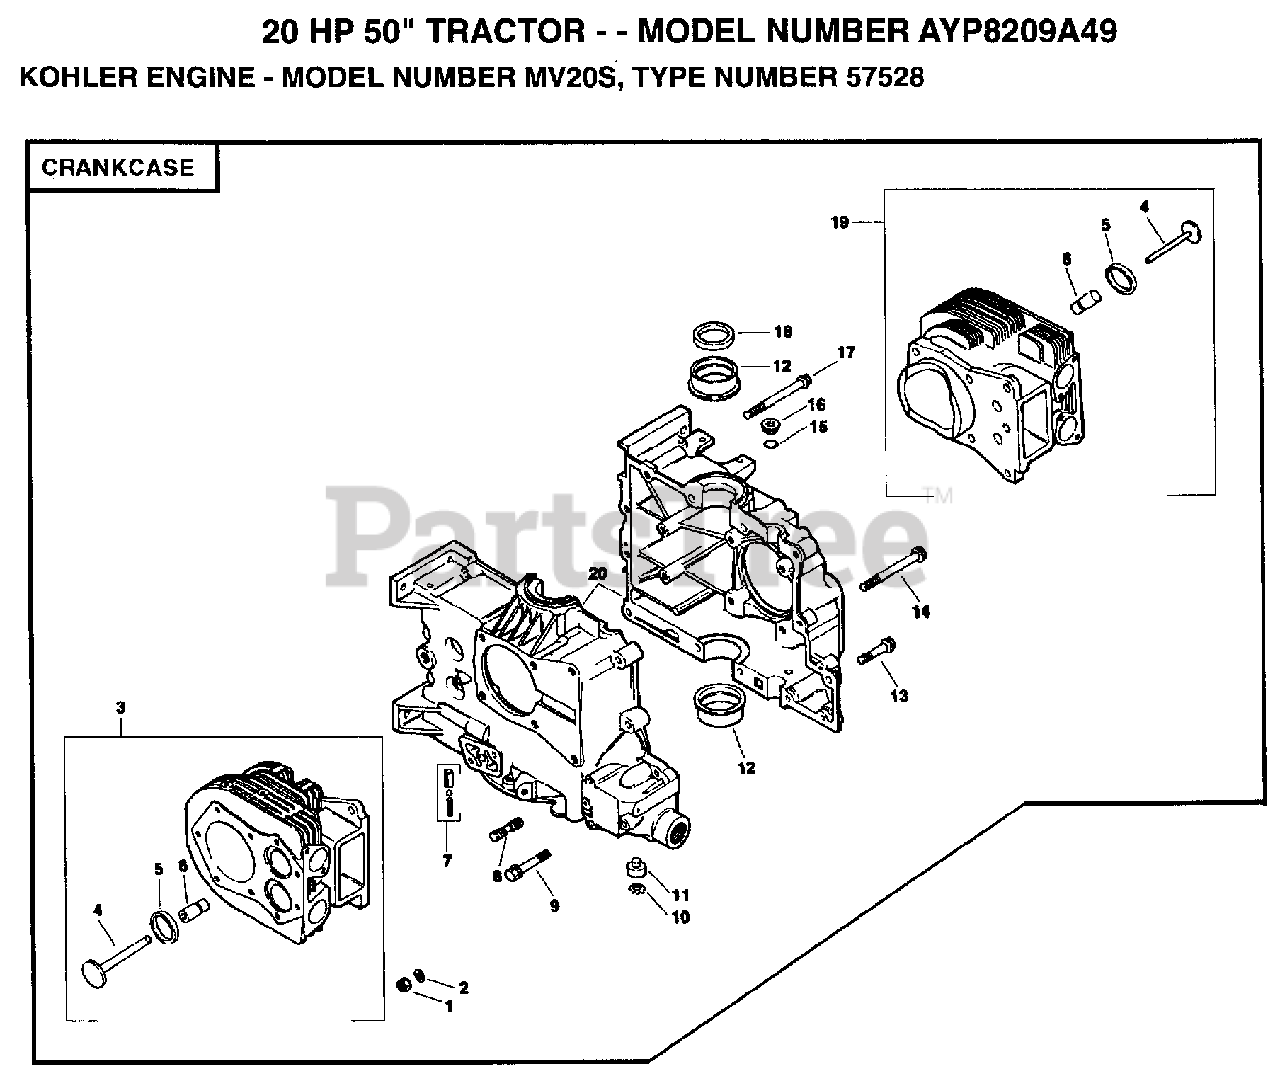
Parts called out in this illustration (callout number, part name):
1	NUT
3	KIT #1 CY. BARREL
4	VALVE EXHAUST
4	CLAMP
5	SCREW
6	PLUG
7	WASHER
8	SCREW, 5/16-18X1-1/4 (4)
10	RING, RETAINING
11	STRAP
12	SCREW
14	KIT, CARB. W/GASKET
15	GASKET
16	SCREW, SLT. #6-40X1/4
17	BRAKET, SOLENOID
18	KIT, SOLENOID
19	KIT #2 CY. BARREL
20	ROD, SOLENOID
22	GASKET, NEEDLE SEAT
24	GASKET, AIR CLEANER
25	WASHER, INTERNAL TOOTH
26	NUT
29	SHAFT, THTLE,W/LEVER & SEAL
44	SCREW, BOWL RETAINER
